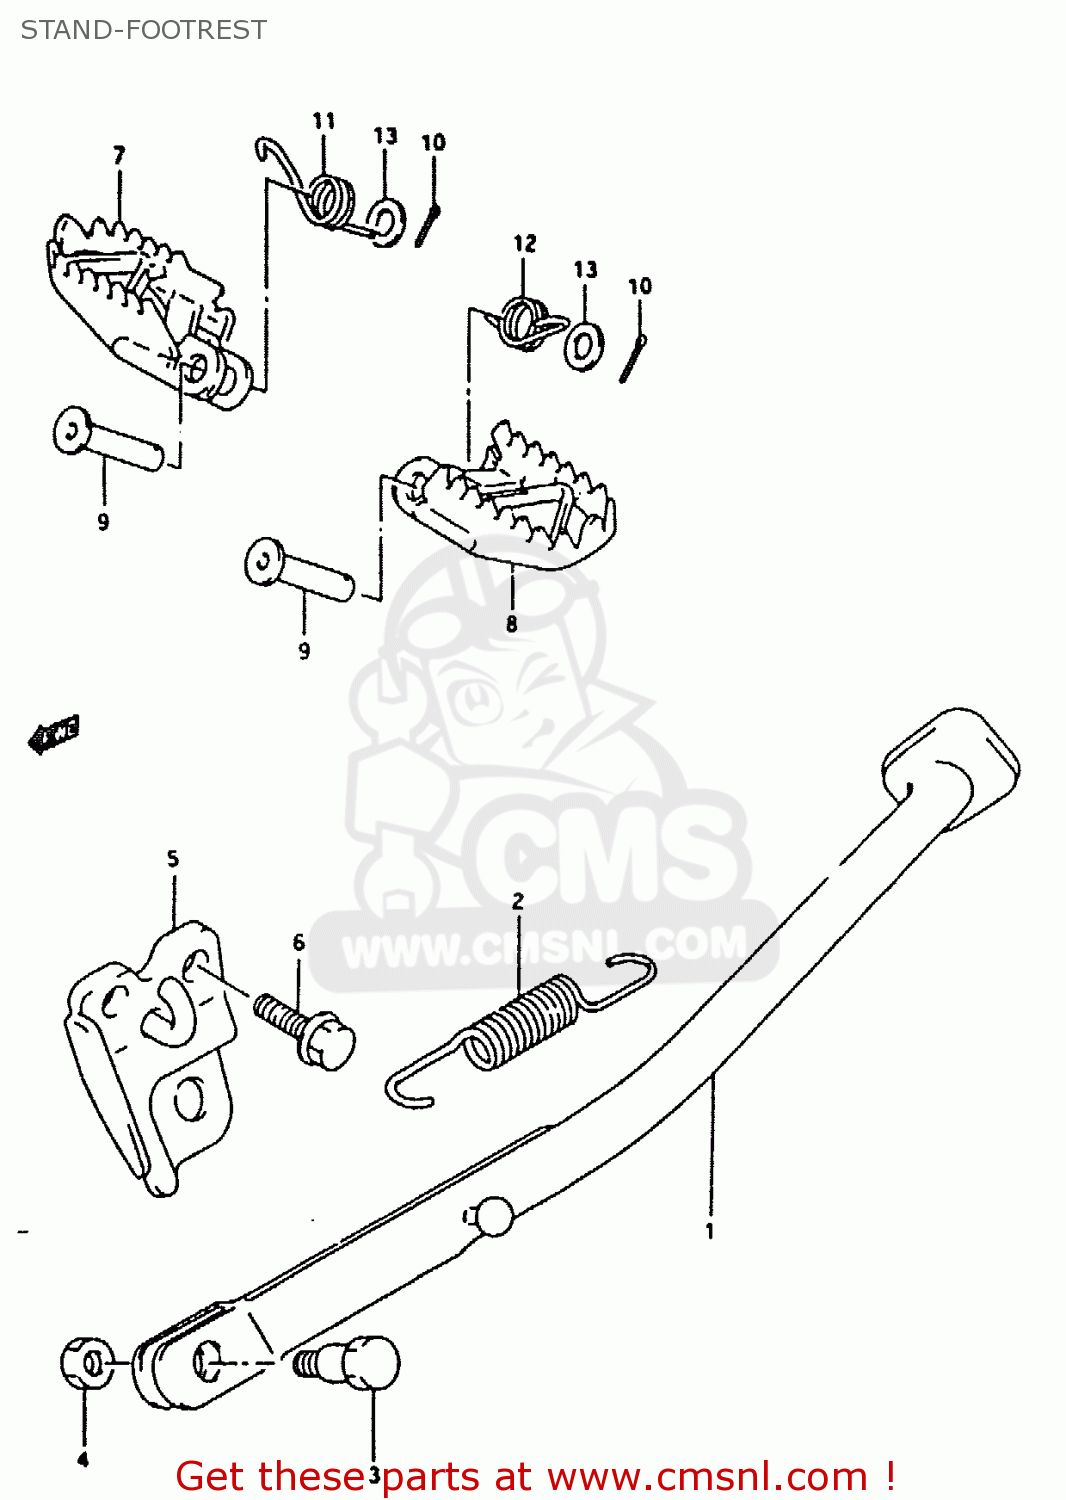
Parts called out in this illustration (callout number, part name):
1	STAND,PROP(SILVER)
2	SPRING
3	BOLT(10X30)
4	NUT
5	BRACKET,PROP STAND
6	BOLT(10X25)
7	FOOTREST,R
8	FOOTREST,L
9	PIN(10X41.5)
10	PIN 25X20
11	SPRING
12	SPRING
13	SPRING
14	WASHER
